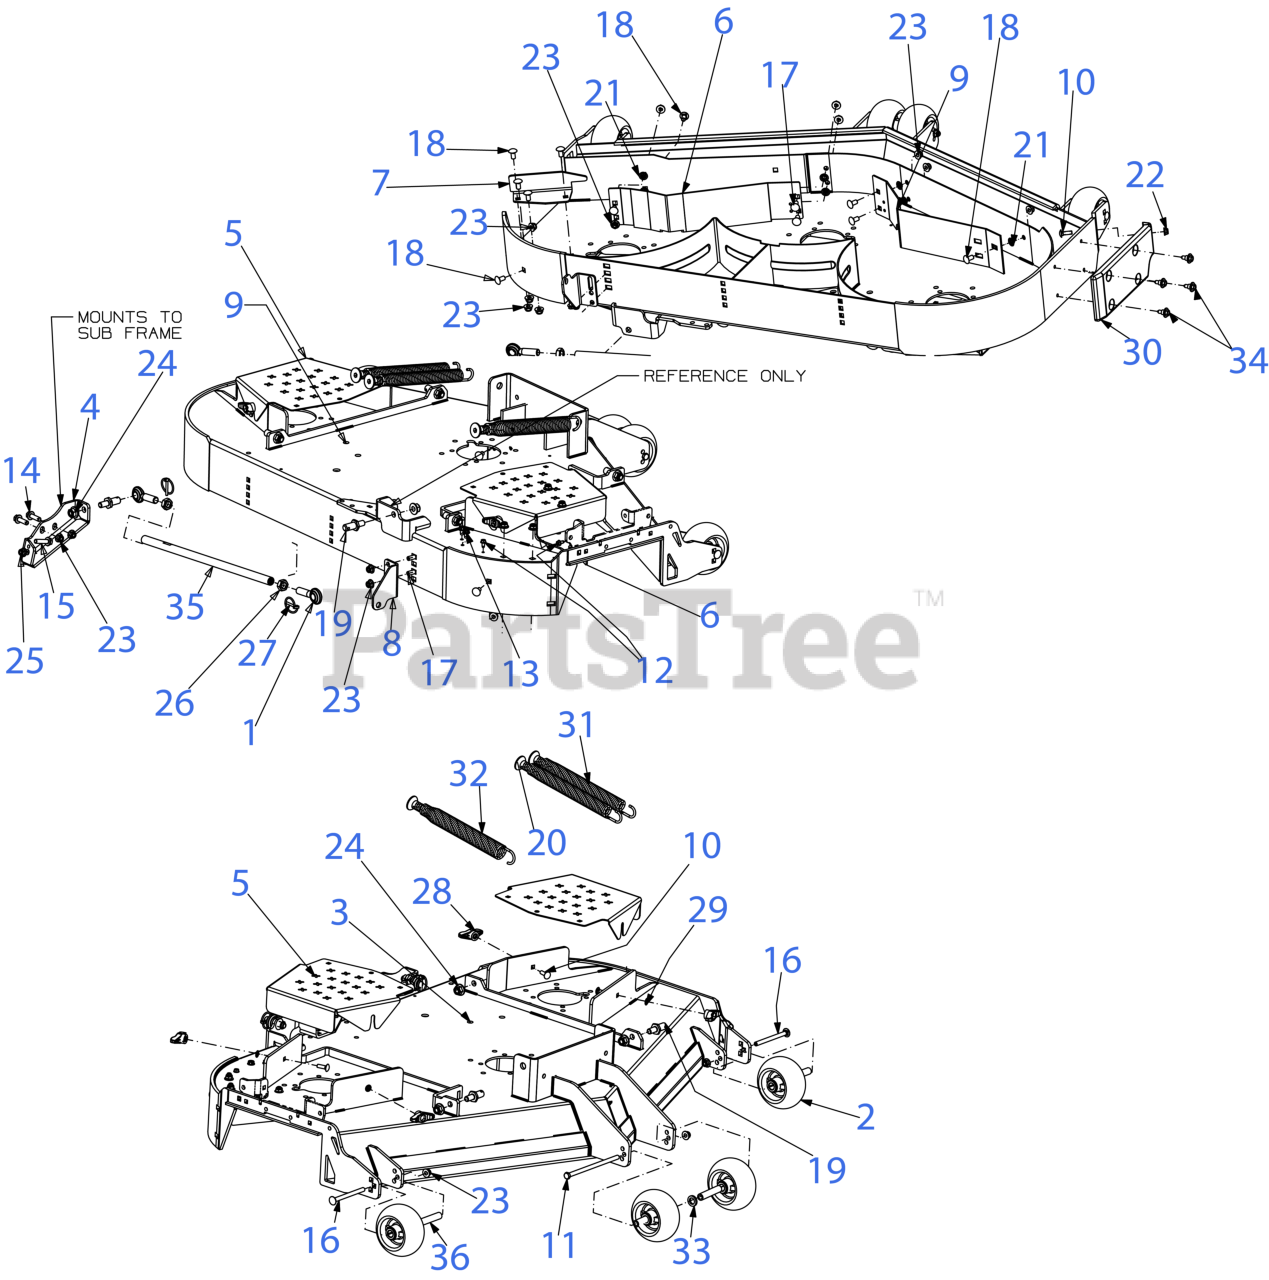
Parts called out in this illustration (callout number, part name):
1	MALE ROD END
2	5" DIA DECK WHEEL COMPLETE
2	WHEEL BUSHING
3	54" FAB DECK SHELL
4	STABILIZER MOUNTING BRACKET
5	DECK BELT COVER
6	DECK BAFFLE
7	DECK CHUTE BAFFLE
8	REAR ROLLER BRACKET (RH)
10	CARRIAGE BOLT 5/16-18 x 1.00
11	SCREW 3/8-16 x 7.25 GR5
12	SCREW 1/4-20 X.500
13	SCREW 5/16-18 x .500
14	SCREW 3/8-16 x 1.25 GR5
15	HEX HEAD BOLT (3/8-16:1.50 GR8)
16	CARRIAGE BOLT 3/8-16 x 4.25 GR5
17	CARRIAGE BOLT 3/8-16 x 1.00 GR5
18	CARRIAGE BOLT 3/8-16 x .75
20	SPRING INSERT SCREW
22	FLANGE LOCK NUT 5/16-18
25	LOCK NUT (3/8-16)
26	HEX JAM NUT 5/8-18
27	LYNCH PIN .1875
28	WING KNOB 5/16-18
30	DECK SKID PLATE (LH)
31	EXTENTION SPRING 1.20 x 11.35
32	EXTENSION SPRING 1.44 OD x 11.36
33	FLAT WASHER .632X1.00X.16
34	SHOULDER SCREW .43X.29X5/16-18 TT
35	TUBE .565 X .750 X 18.75"LG
36	WHEEL SPACER .38ID x 3.04LG
